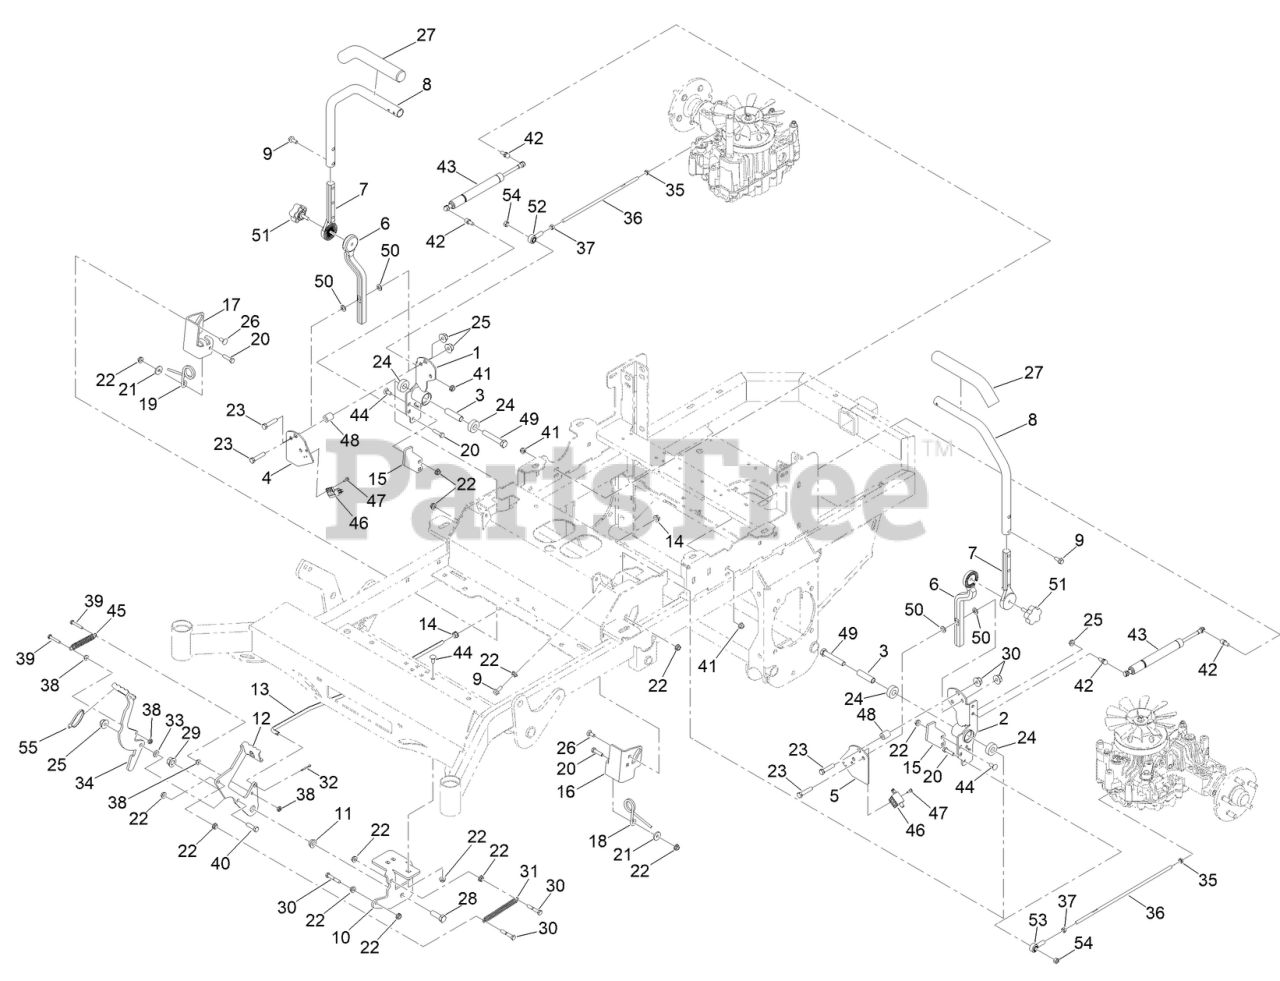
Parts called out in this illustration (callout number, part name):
1	MOTION CONTROL BRKT
2	MOTION CONTROL BRKT
3	MWR DRIVE ARM HUB / DECK LIFT ARM SPACER
4	RT CONTROL ARM LIMIT SWITCH PLATE PAINT
5	LT CONTROL ARM LIMIT SWITCH PLATE PAINT
6	ADJUSTABLE LWR DRIVE ARM
7	ADJUSTABLE UPP DRIVE ARM
8	MOWER DRIVE HANDLE TUBE ABC
9	SCREW-HHF
10	MWR FRAME BRAKE MTG BRKT PAINT
11	1/2IN ID X 3/4IN OD X 3/8IN FLANGE BUSH
12	MWR BRAKE LOCK LEVER ASSY PAINTED
13	TTQ 1310 BRAKE ROD
14	3/8-16 HEX FLANGE NUT W/SERR ZINC YELLOW
15	REVERSE DETENT KICK PLATE
16	REVERSE DENTENT SPRING BASE (LH)
17	REVERSE DENTENT SPRING BASE (RH)
18	SPRING- LT REVERSE DETENT
19	SPRING-TORSION
20	SCREW-HH
21	STRIKER POST FENDER WASHER
23	3/8-16 X 1-3/4 HEX C/S GR 2 ZINC
24	5/8IN ID X 1-3/8IN OD X 7/16IN THK BRG
25	3/8-16 NYLON INSERT FLANGE L/NUT YZ
26	5/16-18 X 1 CARRIAGE BOLT GR 8 YZ
27	CONTROL ARM HANDLE GRIP
28	SCREW-HH
29	NUT-LOCK
31	2020 MWR BRAKE PEDAL TENSION SPRING
32	PIN-COTTER
33	3/8 ID X 3/4 OD X .125 THK BRONZE WASHER
34	MWR BRAKE UNLOCK LEVER ASSY PAINTED
35	NUT-JAM
36	1310 TTQ DRIVE ARM ROD
38	1/4-20 HEX FLANGE NUT
39	1/4-20 X 1-1/4 HEX C/S GR 2 ZINC
40	SCREW-HH
41	5/16-18 NYLON INSERT FLANGE L/NUT ZC
42	5/16-18X1.286 DAMPER BALL STUD (.562 TL)
43	CONTROL ARM DAMPER
44	BOLT-CARR
45	MWR BRAKE PEDAL RELEASE SPRING
46	NO PLUNGER LIMIT SWITCH
47	8-32 X 1/2 IND. HWH SLOT TYPE F TCS ZINC
48	MWR DRIVE ARM SPACER
49	1/2-13 X 3 HEX C/S GR 5 ZINC W/LOCTITE
50	3/8 X 3/4 BRONZE WASHER
51	5/16-18 X 1 SL 5-LOBE MALE ST KNOB 1.90
52	5/16-24 SPHER ROD END ZINC LH THD FEM
53	5/16-24 SPHER ROD END ZINC RH THD FEM
54	5/16-24 NYL INS L/N GR.8 ZC/YEL
55	6IN (40 LB) CABLE TIE NYLON UV
